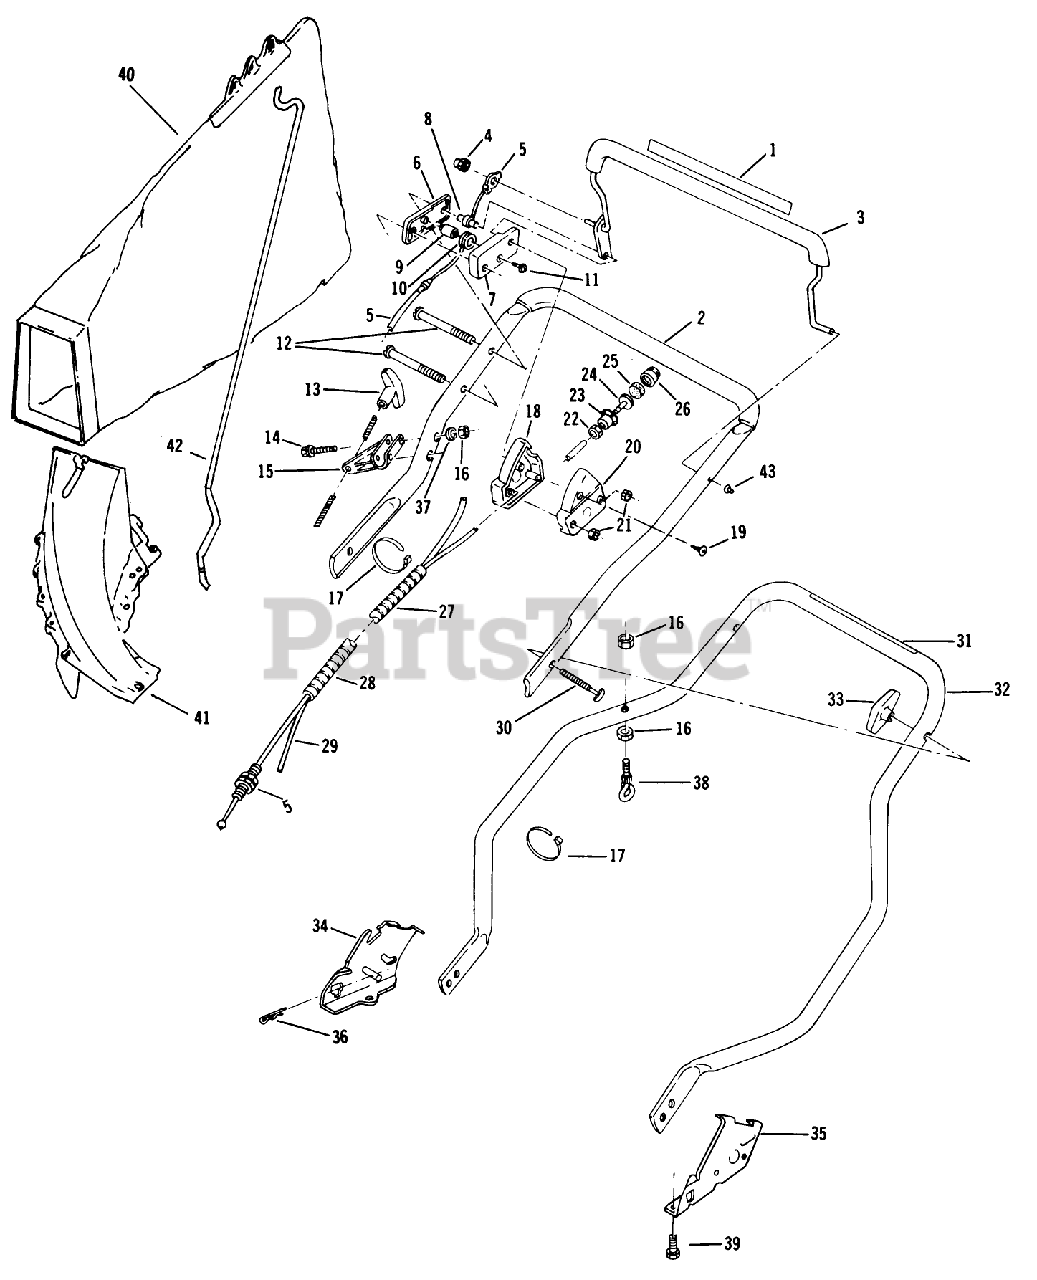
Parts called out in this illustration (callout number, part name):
4	NUT ACORN
8	COLUMN
9	PIN SKF
11	SCREW
13	HANDLE,STARTER
16	LOCKNUT E
19	SCREW LAWRENCE
21	NUT C/LOCK E
22	LOCKNUT S
25	FILTER S
30	BOLT QUALITY
33	NUT-WING
36	HAIR PIN
37	WASHER
38	EYE BOLT WAS MFG
39	SCREW
40	89802 LB WHOLE GOODS
42	ROD GRASSBAG
